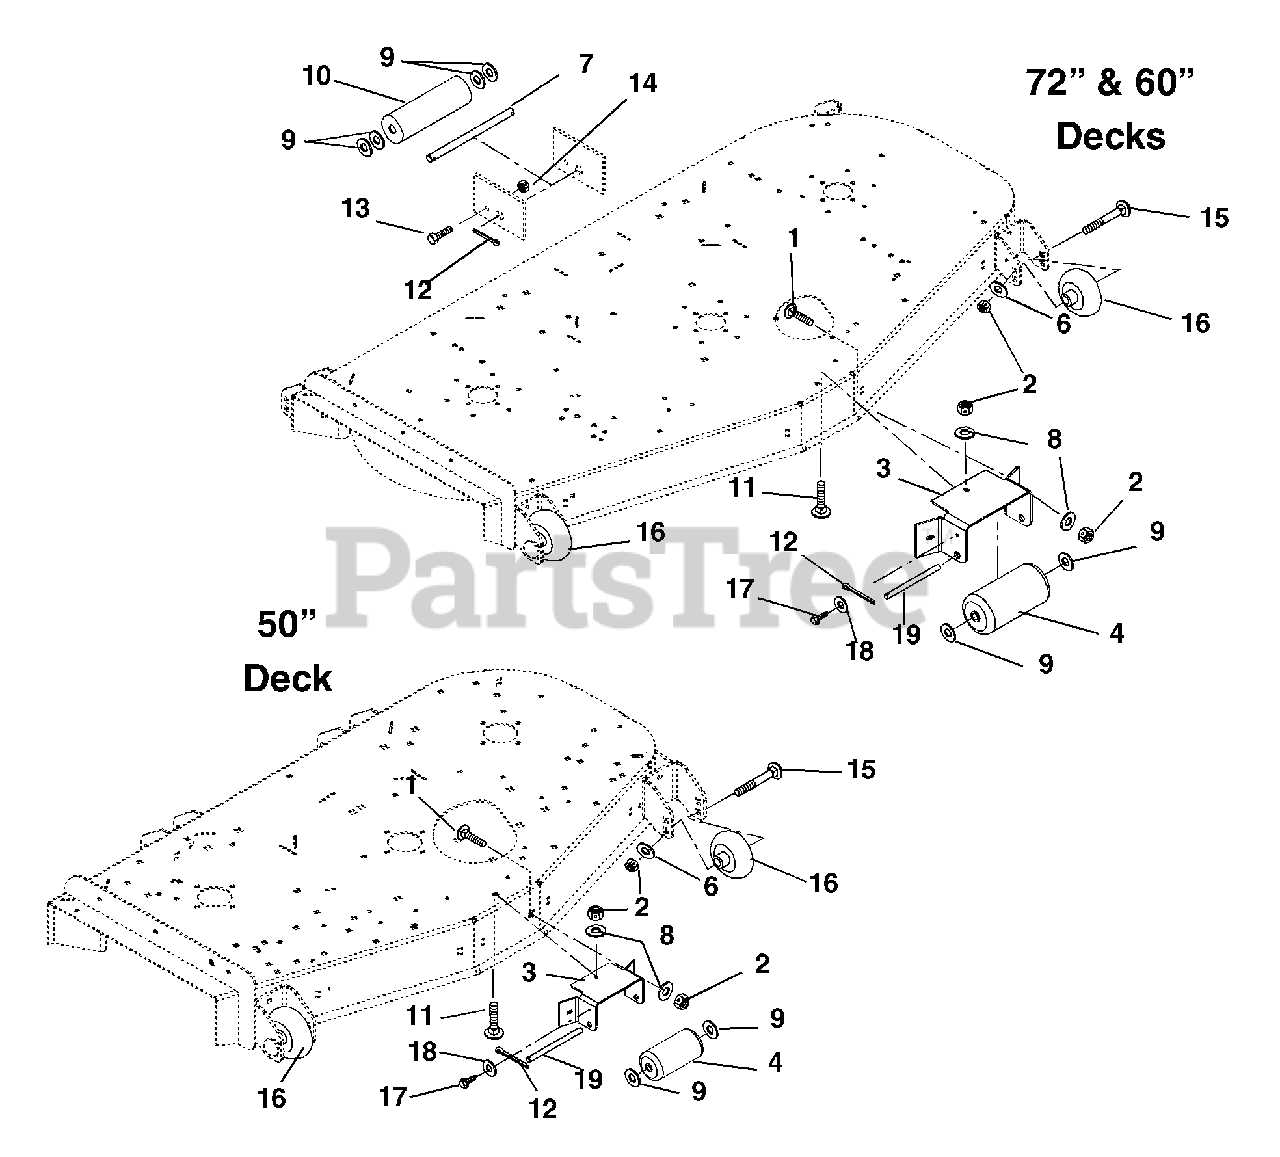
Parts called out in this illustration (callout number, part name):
1	Bolt-Round Head Square Neck .38-16 x 1.00 Grade 5p
2	Nut-Locking-Nylon .38-16
3	Bracket, Anti-Scalp Roller
5	Nut-Locking-Nylon .50-13
6	Washer-Flat-Steel .531 x 1.06 x .095
7	Shaft, Center Roller (60" & 72" Deck)
8	Washer-Flat-Steel .406 x .812 x .065
9	Washer-Flat-Steel .656 x 1.31 x .095 (72" & 60" Deck)
9	Washer-Flat-Steel .656 x 1.31 x .095 (50" Deck)
10	Roller, Gage (60" & 72" Deck)
11	Bolt-Round Head Square Neck .38-16 x 1.25 Grade 5
12	Pin-Cotter .25 x 2.00 (72" & 60" Deck)
12	Pin-Cotter .25 x 2.00 (50" Deck)
13	Bolt-Hex .25-20 x .75 Grade 5 (72" & 60" Deck)
14	Nut-Locking-Center .25-20 (72" & 60" Deck)
15	Bolt-Round Head Square Neck .50-13 x 5.00 Grade 2
16	Wheel, 3 x 5
17	Screw-Self Tapping .25-20 x .50 x Hex Washer Head
18	Washer-Flat-Steel .281 x .62 x .065
